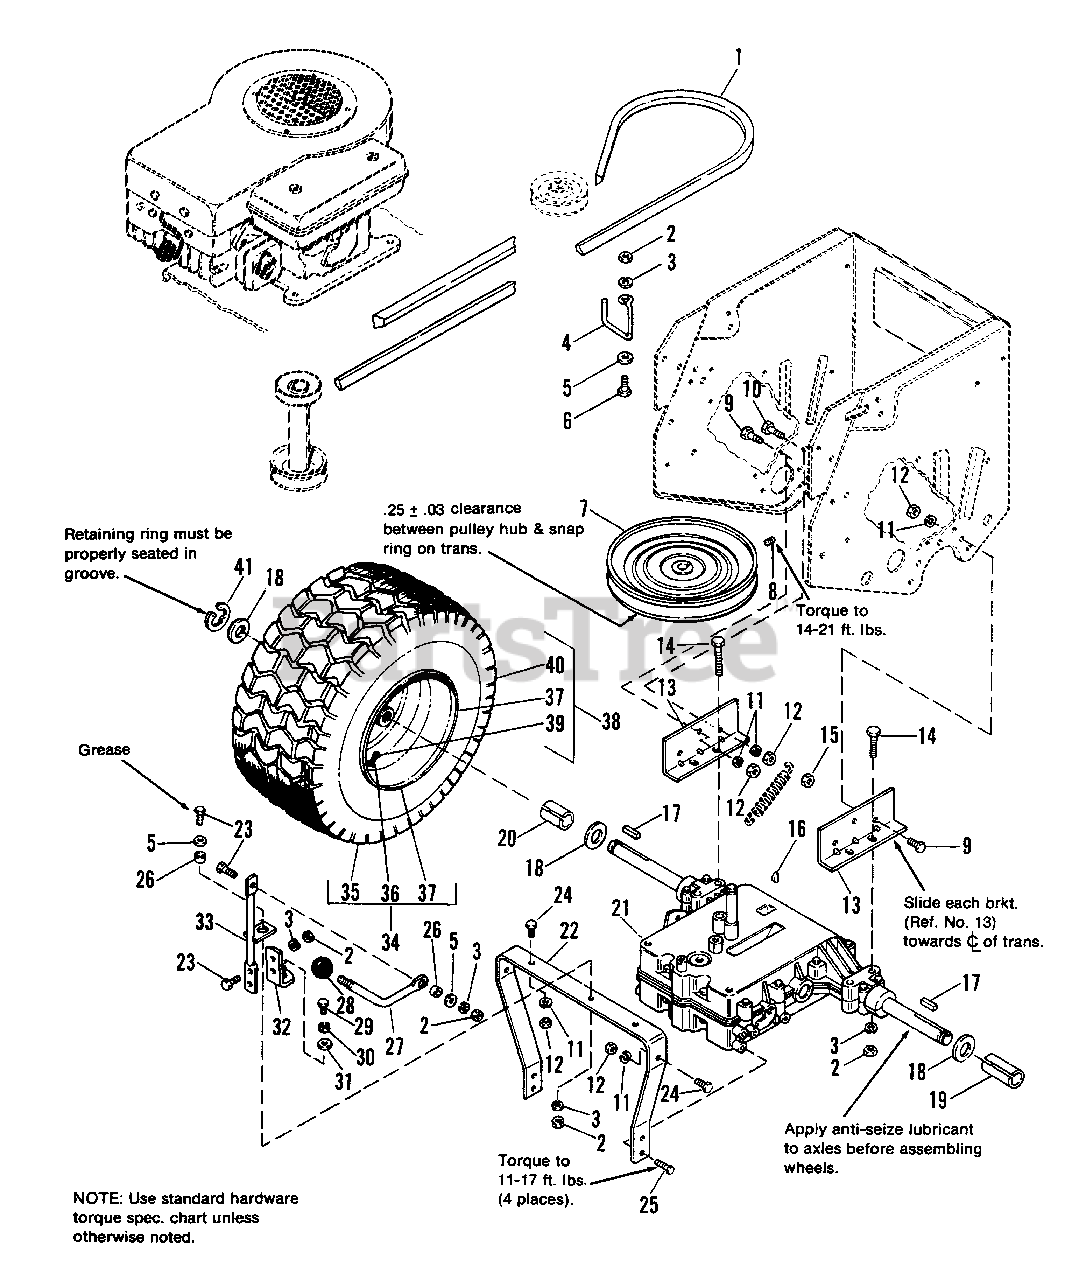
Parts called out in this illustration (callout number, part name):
2	NUT, Hex, 5/16-18
3	LOCKWASHER, 5/16
5	WASHER, 5/16
6	CAPSCREW, Hex, 5/16-18 x 1
7	PULLEY ASSY., Transmission
8	SETSCREW, 5/16-18 x 1/2
9	CAPSCREW, Hex, 3/8-16 x 3/4
10	CAPSCREW, Hex, 3/8-16 x 1-1/4
11	LOCKWASHER, 3/8
12	LOCKNUT, Hex, 3/8-16
13	SUPPORT, Transmission, Rear
14	CAPSCREW, Hex, 5/16-18 x 2-1/4
15	LOCKNUT, Hex, 3/8-16
16	KEY, Woodruff, #9
17	KEY, 3/16 x 3/16 x 1-1/2
18	WASHER, 25/32 x 1-1/8 x 16 Ga.
21	TRANSAXLE, 5 Speed, Peerless
22	SUPPORT, Transmission, Front
23	CAPSCREW, Hex, 5/16-18 x 7/8
24	CAPSCREW, Hex, 3/8-16 x 7/8
25	SCREW, Taptite, 5/16-18 x 5/8
28	KNOB, Ball, Shift
29	CAPSCREW, Hex, 1/4-28 x 5/8
30	LOCKWASHER, 1/4
31	WASHER, Plain, 3/16
32	LINK, Shift, Lower
33	SHIFT LINK ASSY., Upper
34	WHEEL & TIRE ASSY., 18 x 8-1/2-9 (1690456 only)
35	* TIRE, 18 x 8-1/2-8, Goodyear (1690456 only)
35	TIRE, 18 x 8-1/2-8, Carlisle (1690456 only)
36	VALVE (1690456 only)
38	WHEEL & TIRE ASSY., 18 x 9-1/2-8 (1690458 only)
39	VALVE (1690458 only)
40	* TIRE, 18 x 9-1/2-8, Goodyear or Carlisle (1690458 only)
